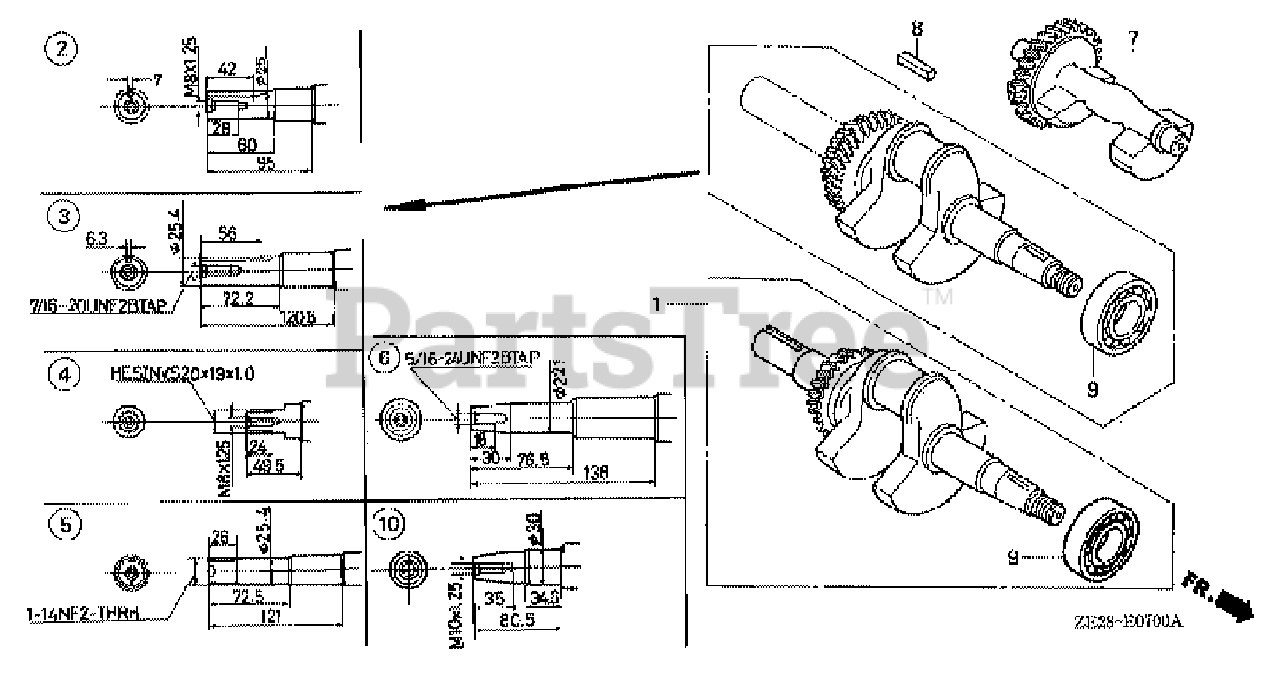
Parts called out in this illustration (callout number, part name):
4	CRANKSHAFT (L-TYPE)
7	WEIGHT, BALANCER
8	KEY (6.3X6.3X43)
9	BEARING, RADIAL BALL (6206)
